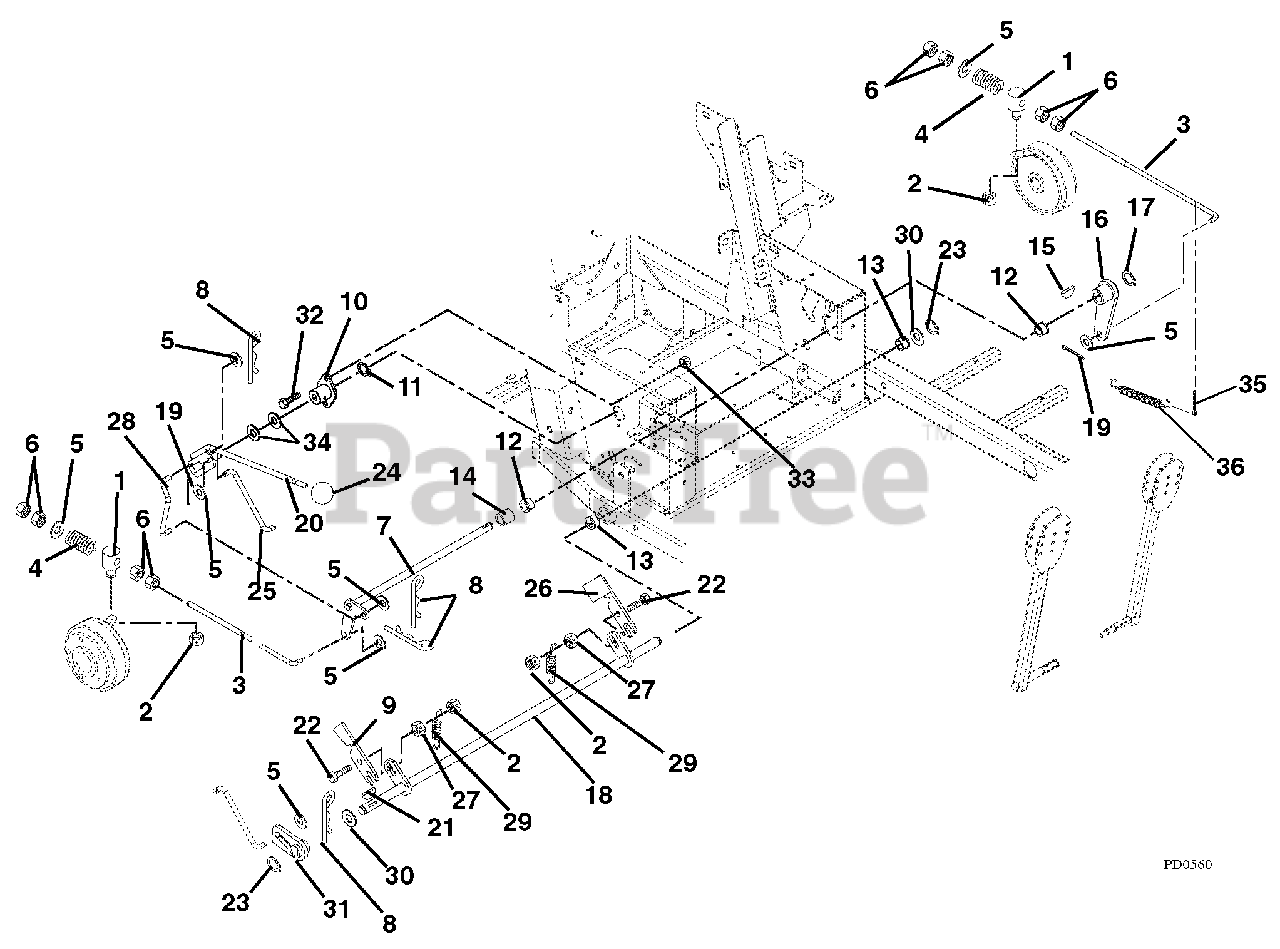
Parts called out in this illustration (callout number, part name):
1	PIN, PIVOT/TRUNNION
2	@NUT-LK-CTR .31-18 YWZC
3	PTO LINK ROD, PRO-150
4	SG-COMP .142 X .710 X 1.75
5	@WSHR-FL-STL.406X.812X.065 YWZ
6	@NUT-HEX .38-16 YWZC
7	WMT, BRAKE CROSS SHAFT
8	PIN-HAIR, ENDRIES #25 YWZC
9	SLIDE, INTERLOCKING BRAKE
10	BUSHING, FLANGED
11	RG-RTNG-EXT .625X.050
12	BSHG-FLG .762X1.0X.580X1.48 NY
13	BSHG-FLG .515X.750X.745X1.00NY
14	BSHG-SLV .750X1.000X.750
15	KEY-WDRF .19X.75 HRD #9
16	WMT, BRAKE ARM
17	RG-RTNG-EXT .689X.078
18	WMT, MECHANICAL BRAKE
19	@PIN-CTR .09X.75 EXTPRSQCT YWZ
20	WMT, BRAKE HANDLE
21	KEY-WDRF .13X.63 HRD#5
22	@BLT-RDHDSQNK .31-18X1.25 G5YZ
23	RG-RTNG-EXT .500X.050 (SNAP)
24	GRIP,HANDLE
25	LINKAGE, BRAKE ACTUATING
26	INTERLOCK, SAFETY SWITCH
27	@NUT-LK-TOP-FLG .31-18 YWZC
28	LINKAGE, BRAKE ACTUATING
29	SG-TENS .063X.44X1.56
30	WSHR-FL-STL .505X1.00X.062YWZC
31	WMT, PARKING BRAKE HUB
32	@BLT-HEX .31-18X.75 GR5 YWZC
33	@NUT-LK-TOP-FLG .31-18 YWZC
34	WSHR-FL-STL .630X1.250X.062 YZ
35	@PIN-CTR .12X.75 EXTPRSQCT YWZ
36	SPRING, EXT
